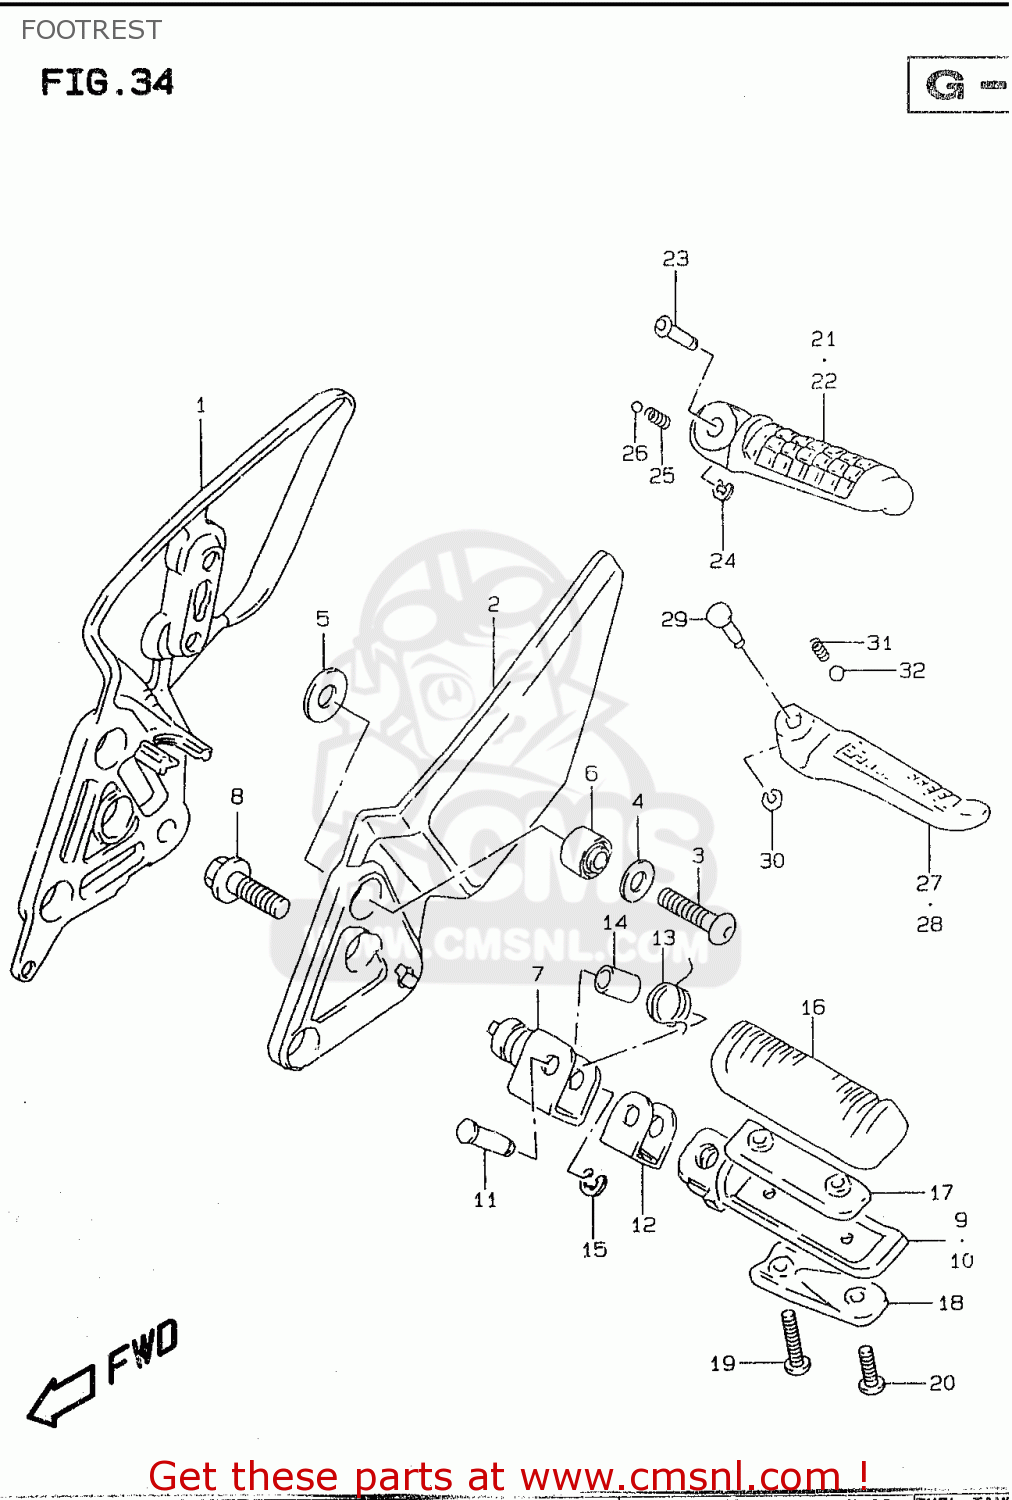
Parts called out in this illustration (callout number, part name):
1	BRACKET,FRONT FOOTREST
2	BRACKET,FRONT FOOTREST
3	BOLT(8X28)
4	WASHER (8.2X24X1.6)
5	WASHER(12.6X24X1.9)
6	BUSH(12X20X16)
7	HOLDER,FOOTREST
8	BOLT(10X28)
9	BAR,FOOTREST,R
10	BAR,FOOTREST,L
11	PIN(8X33.2)
12	CUSHION,FR FOOTREST
13	SPRING
14	SPACER(8.1X12X22)
15	E.RING
16	RUBBER,FOOTREST
17	BAR,FR FOOTREST NO.2
18	BALANCER,FR FOOTREST LWR
19	SCREW
20	SCREW
21	BAR,PILLION FOOTREST,R
22	BAR,PILLION FOOTREST,L
23	PIN
24	E.RING
25	SPRING
26	BALL
27	BAR,PILLION FOOTREST,RIGHT
28	BAR,PILLION FOOTREST,LEFT
29	PIN
30	E-RING
31	SPRING
32	BALL
